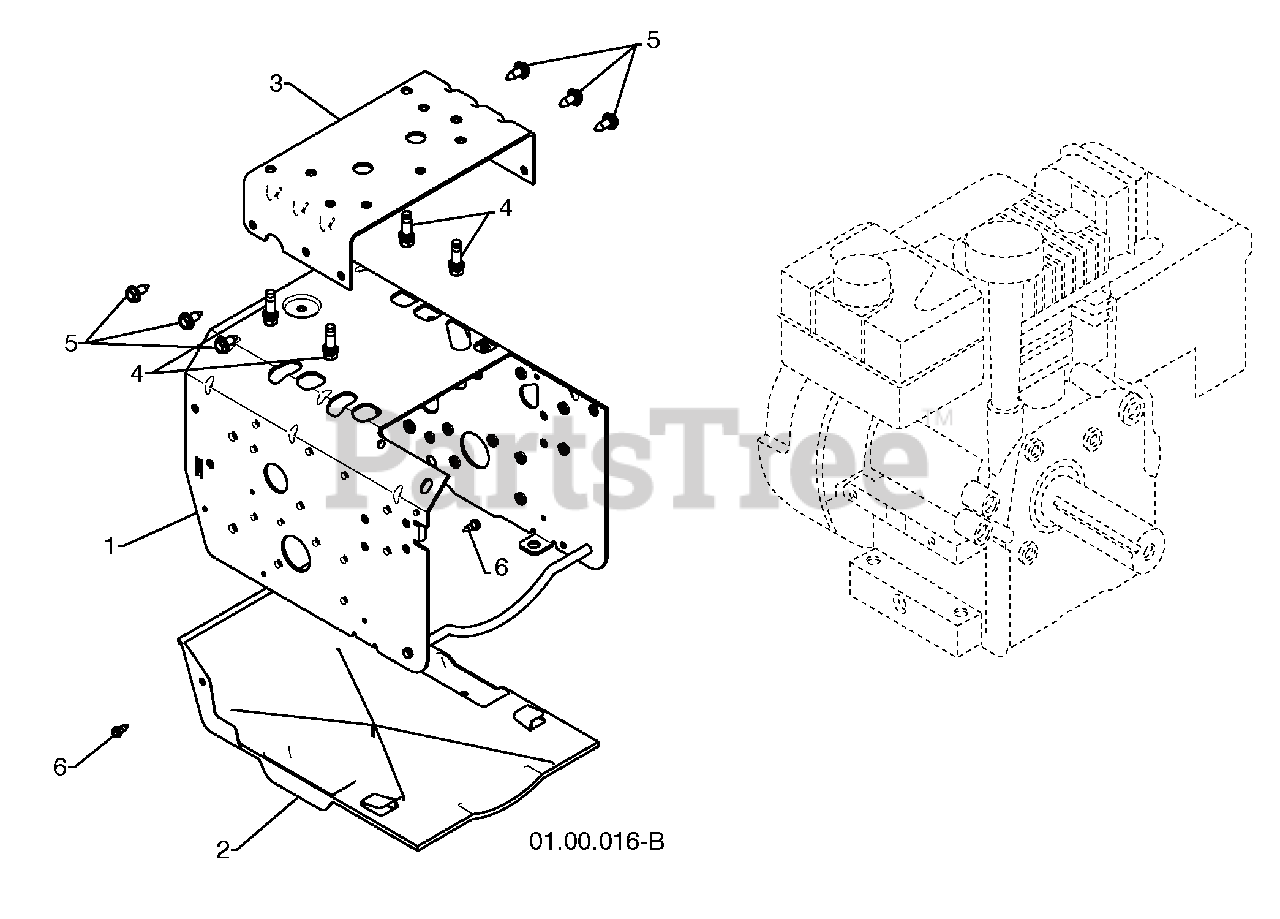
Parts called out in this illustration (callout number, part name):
2	BOTTOM PAN
3	ENGINE MOUNT PLATE
4	BOLT 3/8-16
5	SCREW 5/16-18 X .750
6	SCREW 10-24 X .625
